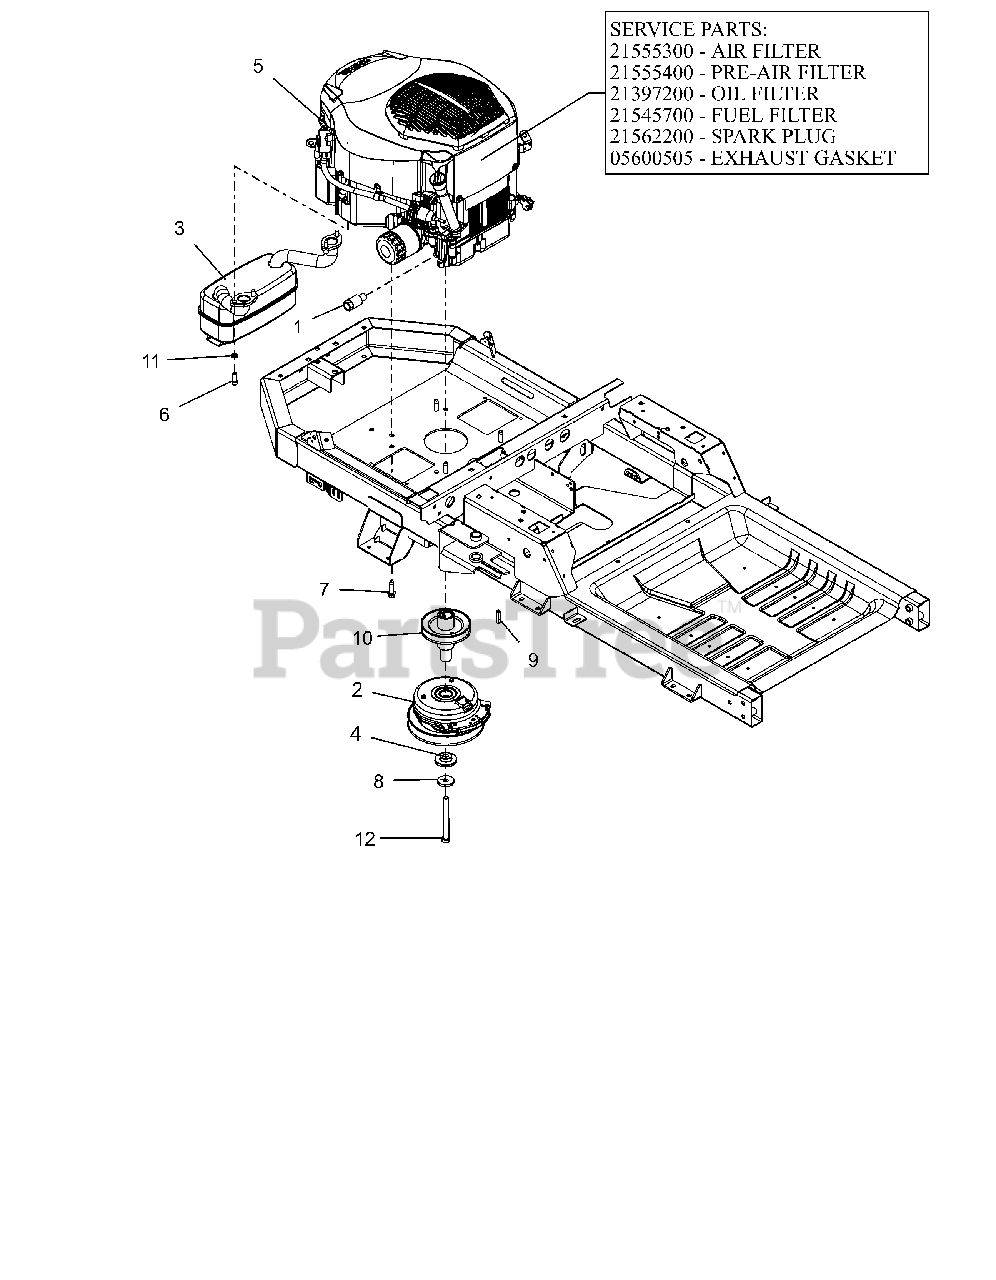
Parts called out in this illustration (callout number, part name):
1	DRAIN, OIL
2	CLUTCH,105FTLB MONOPOLE 6.83"
3	MUFFLER - KOHLER
4	BSHG-FLG .469X1.06X.574X2.0
5	ENGINE-KOHLER PRO 24HP W/SC
5	AIR FILTER, KOHLER
5	PRE CLEANER, KOHLER
5	FILTER, OIL - KOH CV20
5	FILTER-FUEL KOHLER COURAGE PRO
5	PLUG, SPARK (RFI)
5	GASKET, MUFFLER KOHLER TWIN
6	SCR, SKH .312-18X.875 GR8 ZCC
7	SCR,TAP .375-16X1.25HWH TR ZCC
8	WASHER, 7/16" SPRING DISK
9	KEY-SQ .25 X 1.25 X .25 SAE
10	WLDMT, DRIVE SHEAVE-X
11	WSHR,LK-REG .312X.078 ZCC
12	BLT, HEX .44-20X4.50 G8 ZCC NT
